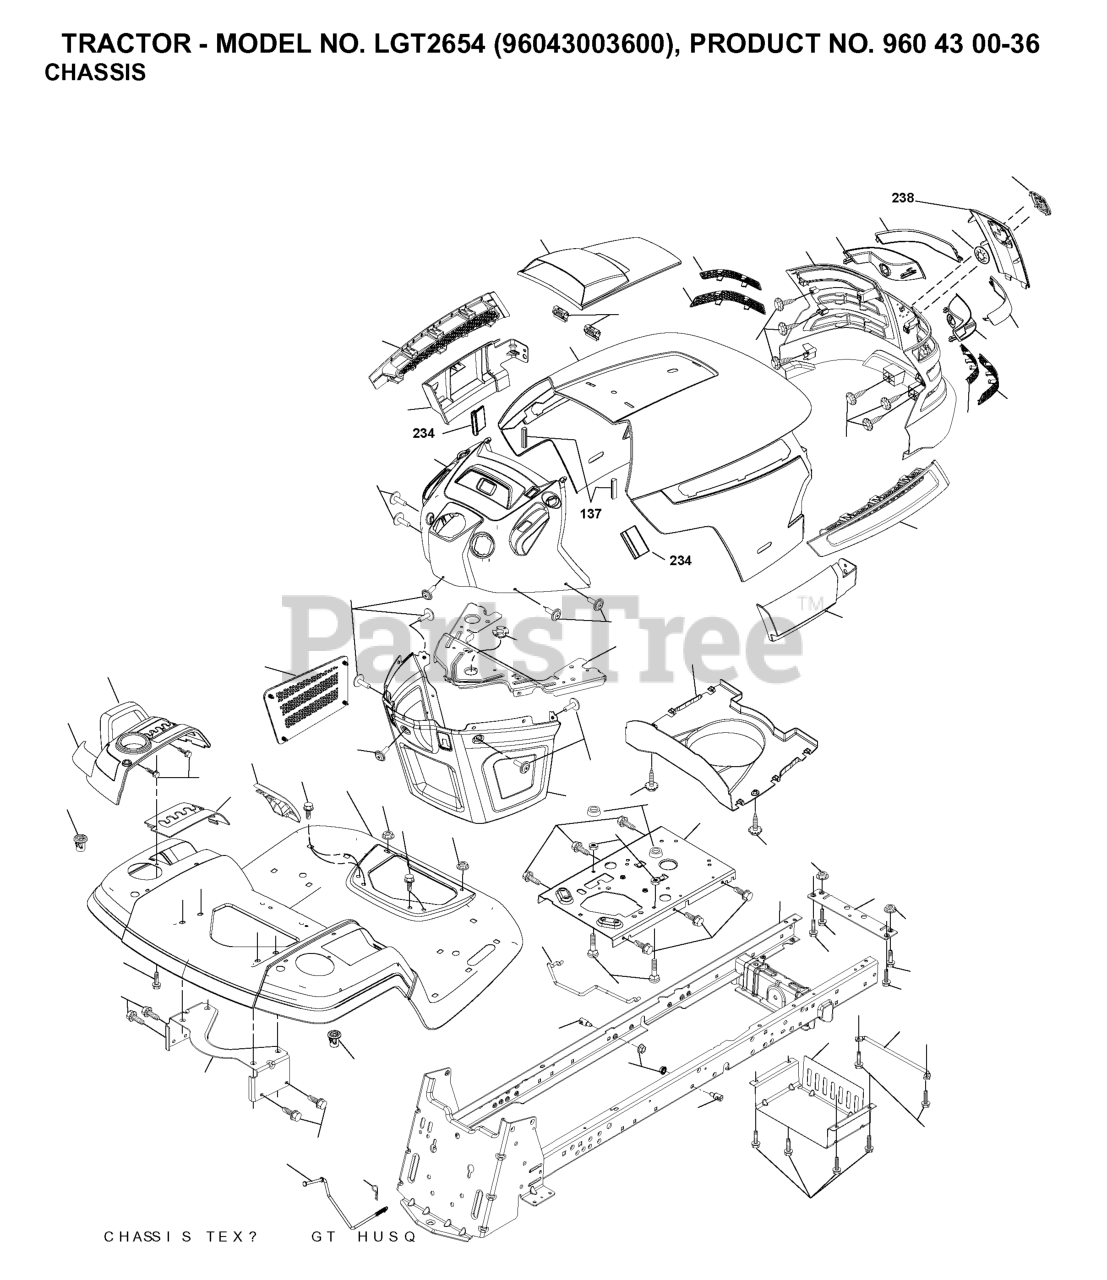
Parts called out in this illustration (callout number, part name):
3	RP LOGO
5	DASH.ASM.HUSQ.GT.E.RECT.W/CK
14	HOOD
15	LENS.LH.TEX.GT.HUSQ.CL
18	GRILL.ASM.HUSQ.TG/CRD.W/TRIM
25	LENS.RH.TEX.GT.HUSQ.CL
34	PLATE.ENGINE.WELDED.CHASSIS
37	FENDER.PNT.TX.GT.CH/FW.ORANGE
52	LOCKNUT
58	BRKT.SUPPORT.FNDR/TANK
68	Screw 5/16-18 x 1/2 Hex, Self Tapping 5/16-18 x 1/2
99	ROD ASM BYPASS
102	RETAINER M
130	SCREW
137	BUMPER DASH
139	Screw 5/16-18 x 1/2 Hex, Self Tapping 5/16-18 x 1/2
150	AIR.DUCT.HOOD.TEX.GT.HUSQ
152	SHIELD.BROWNING.W/TEX
156	SCREW 5/16"
161	CONSOLE.FUEL.WINDOW.HU
162	SCREW.HI-LO.CONSOLE
165	SUPPORT.TANK.REAR.W/TEX
175	PLATE.CROSSMEMBER.HUSQ
176	RP SCREW.10-24X5/8.WSHD
177	BUSHING, STEERING
178	CARGO.ASM.NET.TXGT.W/C
180	CHASSIS.WLDMT.TX.GT.05
181	BUSHING.MNT.FEND.CRGO.
182	DASH.LOWER.COMMON.12V.
189	SCREW
194	NUT.71038.31-18.HEX.NYLOCK
196	RP CONSOLE.ASM.DECKLFT.W/
199	PLATE.DECK.LIFT.HUSQVARNA.GT
202	VENT.SIDE.HOOD.HUSQ.RH.GREY
203	VENT.SIDE.HOOD.HUSQ.LH.GRAY
204	VENT.TOP.HOOD.HUSQVARN
205	SKIRT.HOOD.SIDE.HUSQ.RH.GREY
206	SKIRT.HOOD.SIDE.HUSQ.LH.GREY
207	BEZEL.RH.TEX.GT.HUSQ
208	BEZEL.LH.TEX.GT.HUSQ
209	INSERT.HEX.GRILL.HUSQ.GREY
210	INSERT.HEX.GRILL.HUSQ.
211	INSERT.HEX.GRILL.HUSQ.
212	INSERT.HEX.GRILL.HUSQ.
213	BOLT
214	CLIP.RETAINER.TINNER.
217	ROD PIVOT CHASSIS/HOOD
218	X-PIECE.HOOD.STOP.NON/
219	STUD.FASTNER.W/ANTI-ROTATE
221	REFLECTOR.LH.TEX GT HU
234	BUMPER.HOOD.TEX.HUSQVARNA
235	SPACER FENDER
236	NUT.CENTERLOCK.5/16-
238	TRIM.HUSQ.TG/CRD.SERVICE
239	NUT PUSH M
